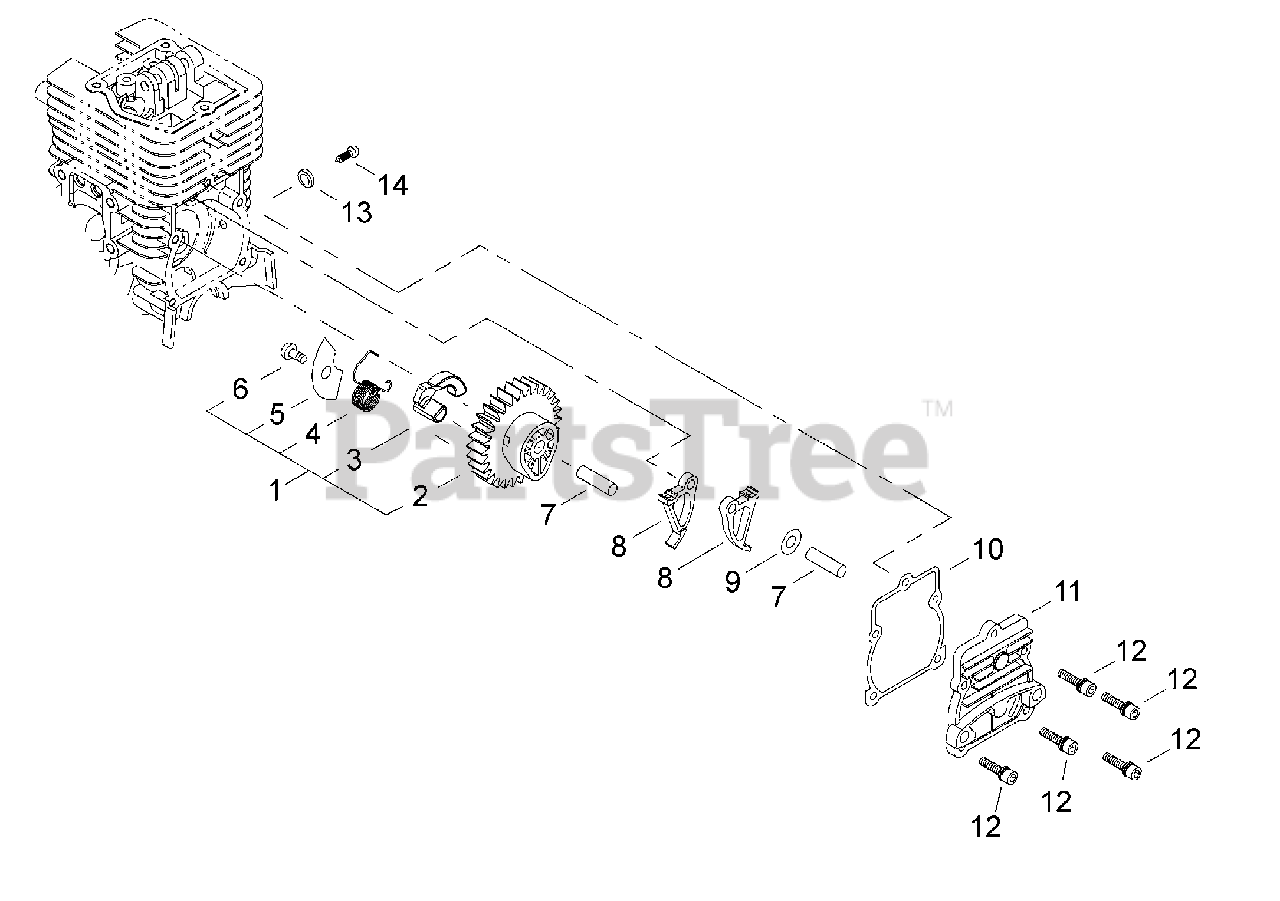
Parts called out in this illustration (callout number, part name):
1	CAM GEAR ASSY
2	GEAR, CAM
3	WEIGHT
4	SPRING
5	COVER, PLATE
6	SCREW - 4X6 -- TAPPING
7	PIN - LOCATING
8	FOLLOWER, CAM
9	WASHER - 5
10	GASKET
11	COVER, CAM GEAR
12	SCREW - 4X14
13	WASHER
14	SCREW - 5
